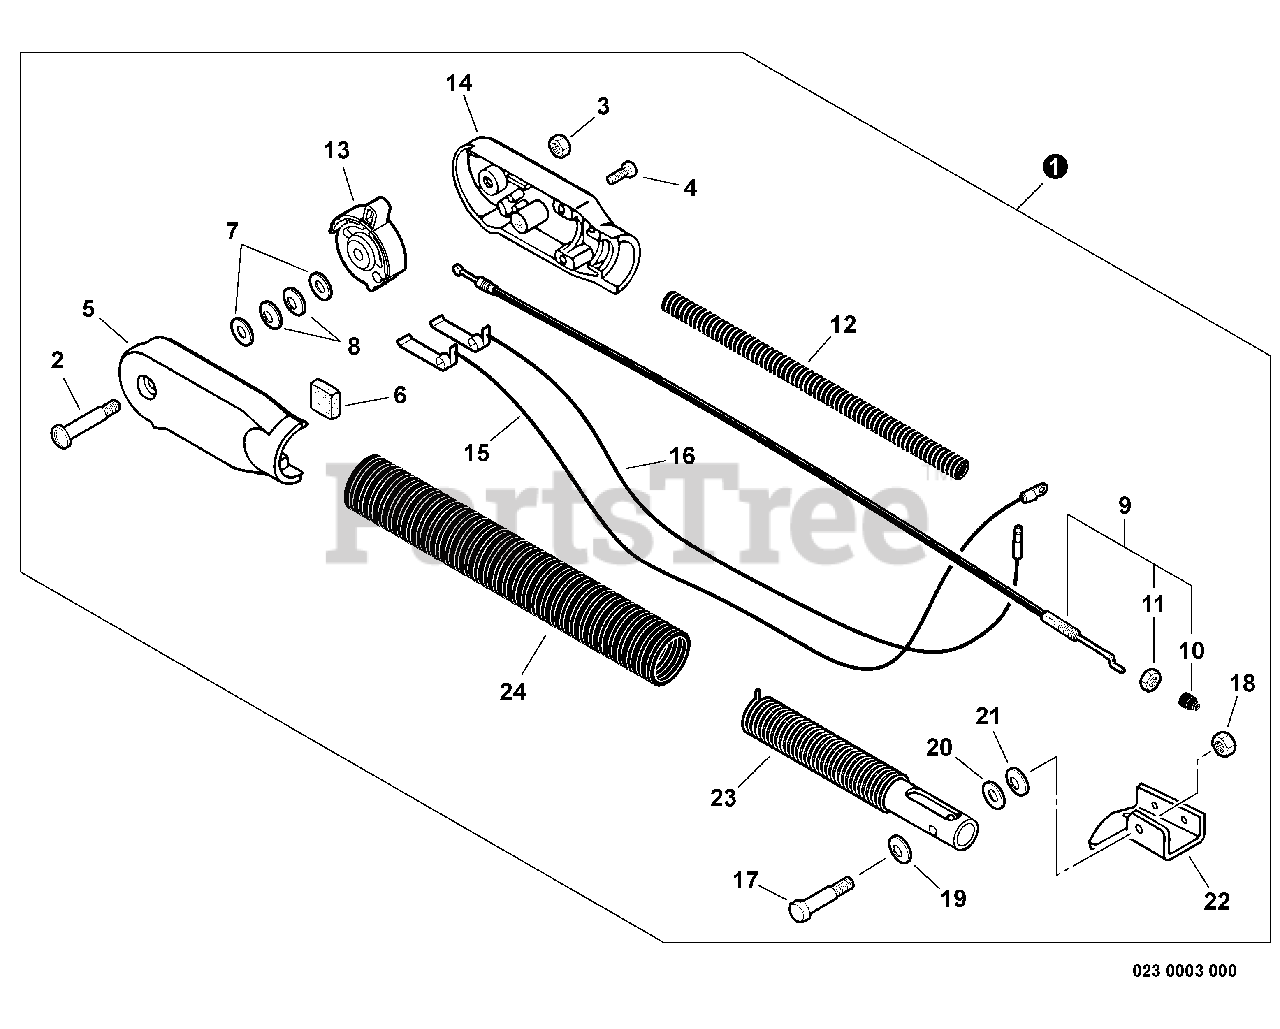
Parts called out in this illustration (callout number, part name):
1	HIP MOUNT THROTTLE CONTROL KIT
2	SCREW - 4
3	LOCKNUT - 4
4	SCREW - 5X20
5	HANDLE, CONTROL - LEFT
6	PAD, FOAM
7	WASHER - 6
8	WASHER - SPRING
9	THROTTLE CABLE ASSY
10	CAP, DUST
11	LOCKNUT - 6
12	TUBE, PROTECTIVE - CORRUGATED
13	LEVER, THROTTLE CONTROL
14	HANDLE, CONTROL - RIGHT
15	LEAD - GROUND
16	LEAD - IGNITION
17	BOLT - 6
18	LOCKNUT - 1/4"
19	WASHER - SPRING
20	WASHER - 8
21	WASHER - SPRING
23	SPRING TUBE ASSY
24	TUBE, OUTER
